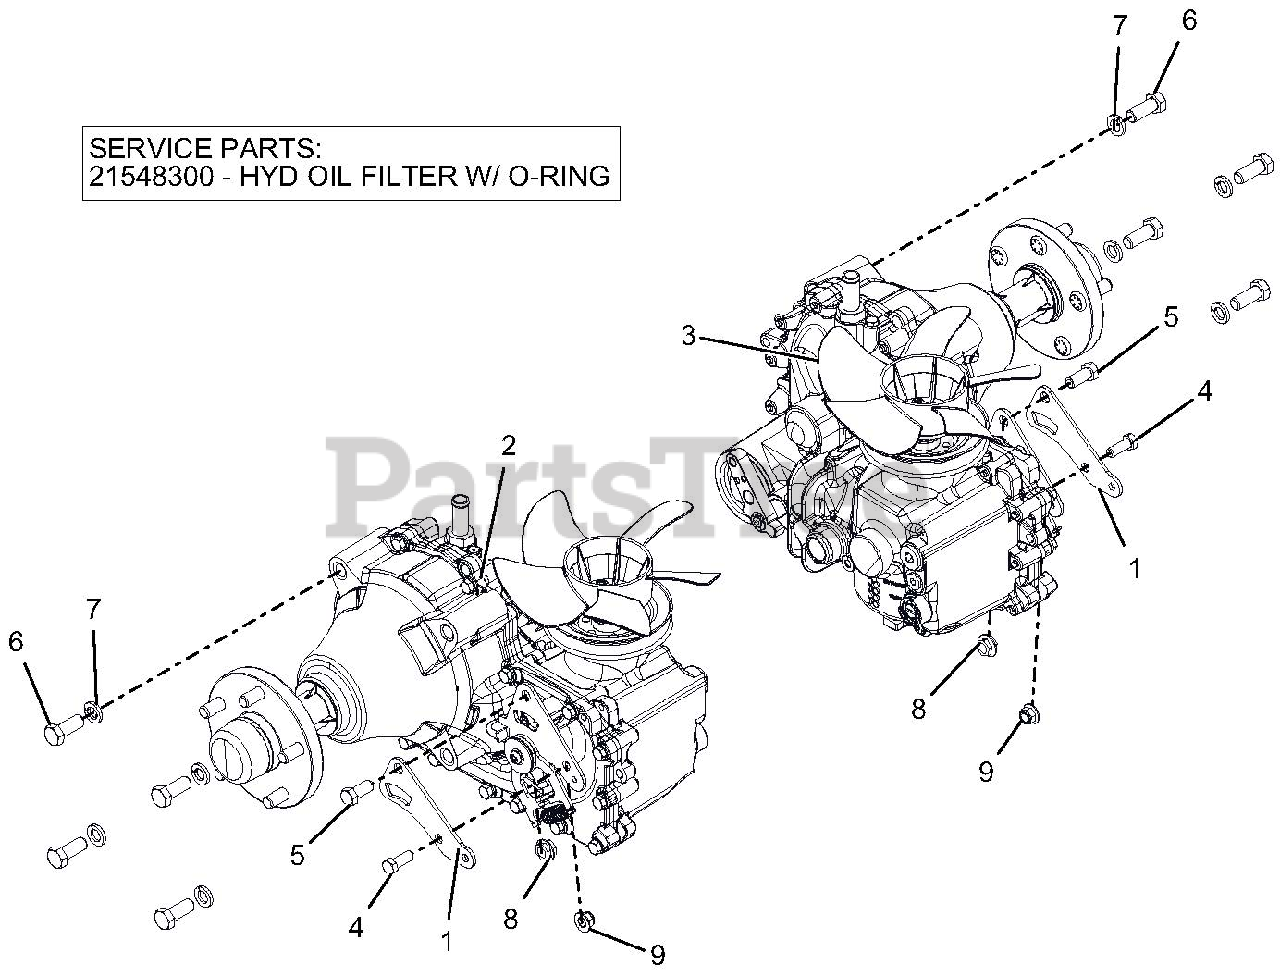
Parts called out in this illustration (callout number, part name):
1	BRKT., CONTROL MTG-BLACK
2	TRANS, R.H. HG ZT-5400
3	TRANS, LH HG ZT-5400
4	BLT-HEX .38-16X1.00 GR5 YWZC
5	BLT-HEX .44-14X1.00 GR5 YWZC
6	BLT-HEX .50-13X1.25 GR5 YWZC
7	WSHR-LK .50X.125 REG YWZC
8	NUT-LK-NYL-FLG .44-14 YWZC
9	NUT-LK-NYL-FLG .38-16 YWZC
10	HYD OIL FILTER W/ O-RING
